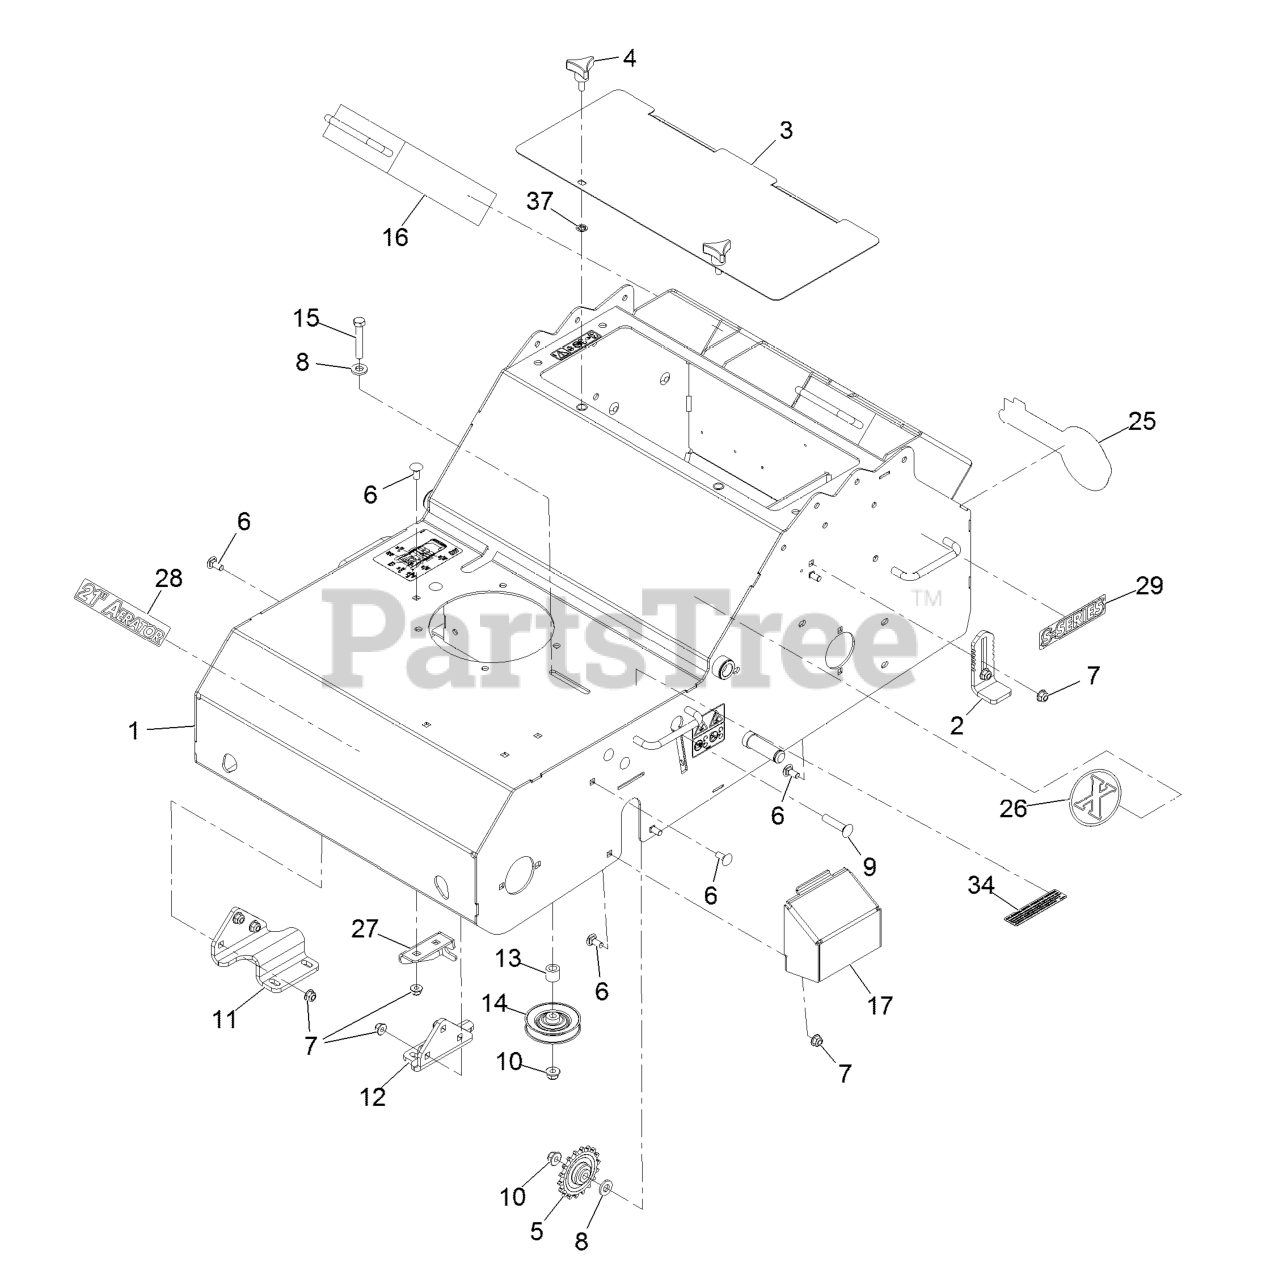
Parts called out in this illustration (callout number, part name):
1	FRAME ASM
2	STOP-DEPTH
3	COVER-ACCESS
5	SPROCKET-IDLER
6	BOLT-CARR
7	NUT-HF, NI
9	SCREW-CARR
10	NUT-HF, NI
11	BRACKET-MOUNT AXLE, RH
12	BRACKET-MOUNT AXLE, LH
13	BUSHING-IDLER
15	SCREW-HH
16	WEIGHT-AERATOR
17	COVER-TRANSAXLE
25	DECAL,EXMARK LOGO
26	DECAL-EXMARK X-LOGO 3.26
27	BRACKET-MOUNTING, CABLE
28	DECAL-AERATOR 21
29	DECAL-S-SERIES
34	DECAL-ARRESTER, SPARK
37	NUT-PUSH
